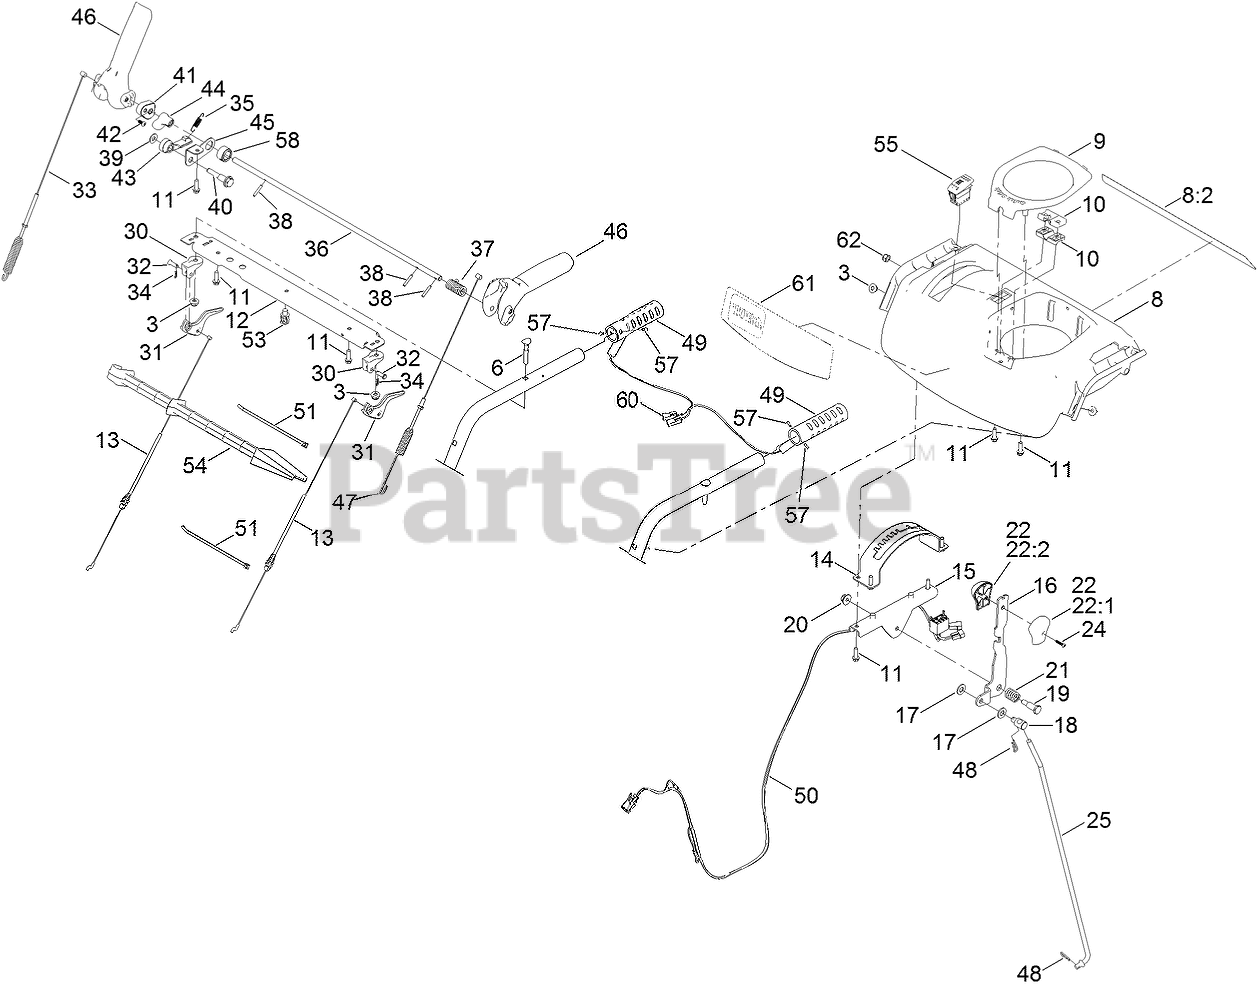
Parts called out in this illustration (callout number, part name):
3	NUT-HF
6	SCREW-HANDLE
8	PANEL-CONTROL
8:2	DECAL-SAFETY
9	COVER-QUICKSTICK
10	SUPPORT-ROD
11	SCREW-PLASTITE, HWH
12	BRACE-CONSOLE
13	CABLE-CLUTCH
14	GATE-SHIFT
15	BRACKET-SHIFT
16	SELECTOR-SPEED
17	WASHER-FLAT
18	TRUNNION-ROD
19	SCREW-SHOULDER, HH
20	NUT-HF
21	SPRING-COMPRESSION
22	SHIFT KNOB ASM
22:1	KNOB-SHIFT, LH
22:2	KNOB-SHIFT, RH
24	SCREW-PPH
25	ROD-SHIFT
30	MOUNT-LEVER, CLUTCH
31	LEVER-CLUTCH
32	PIN-CLEVIS
33	CABLE-AUGER
34	PIN-HAIR
35	SPRING-LOCKOUT, HANDLE
36	ROD-LOCKOUT
37	SPRING-TORSION, HANDLE RETURN
38	PIN-SPRING
39	WASHER-FLAT
40	SCREW-SHOULDER
41	LOCK-HANDLE
42	SCREW-PPH
43	LATCH-LOCKOUT
44	CAM-LOCKOUT
45	LINK-LOCKOUT
46	LEVER-CONTROL
47	CABLE-TRACTION
48	PIN-HAIR
49	GRIP-HANDLE
50	HARNESS-WIRE, LED AND HAND WARMERS
51	TIE-CABLE
53	CLIP-TIE
54	STICK-CLEANOUT
55	SWITCH-ROCKER, ON-NONE-OFF (HEATER)
57	RIVET-POP
58	COLLAR-CAM
60	GRIP-HEATED
61	DECAL-CONSOLE
62	NUT-HEX
